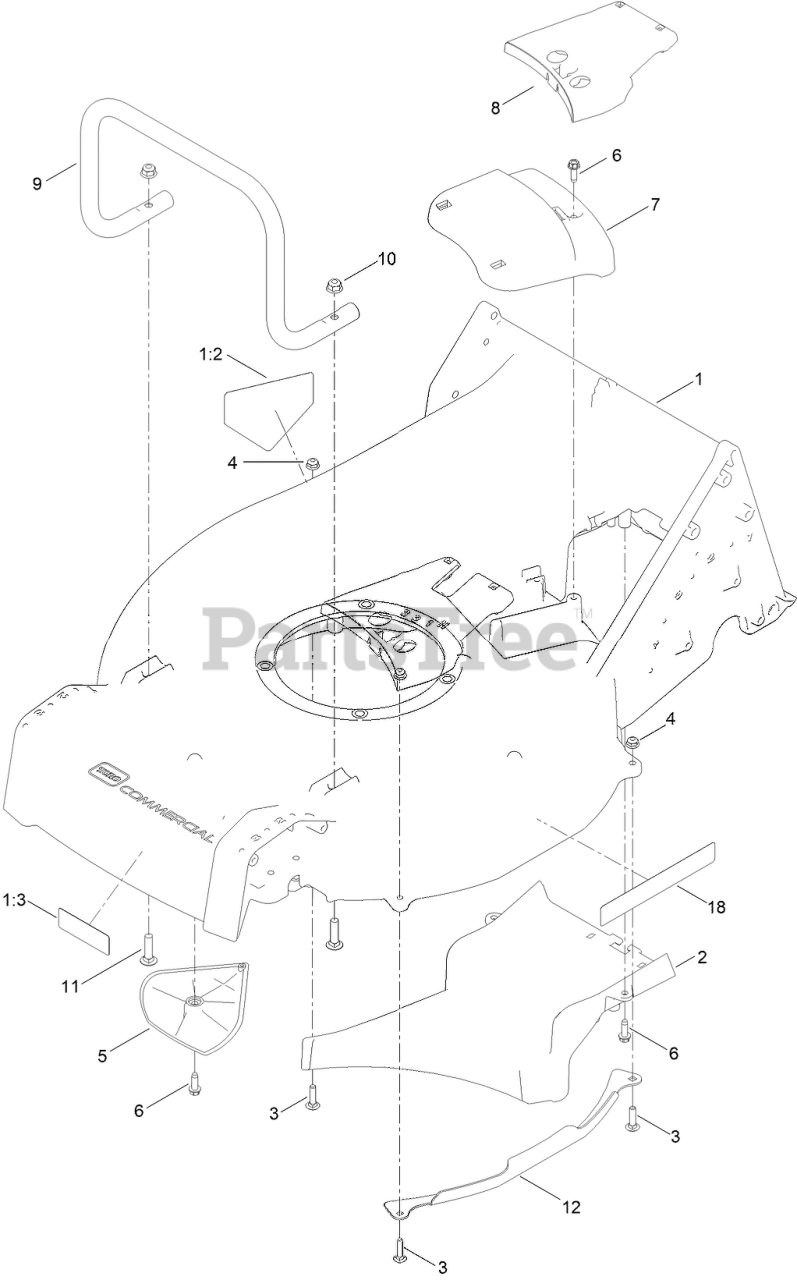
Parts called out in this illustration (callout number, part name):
1	HOUSING ASM
1:2	DECAL-DANGER
1:3	DECAL-WARNING, BLADE
2	FLOOR-CHUTE
3	SCREW-CARR
4	NUT-HF
5	KICKER
6	SCREW-HWHTF
7	COVER-BELT, FRONT
8	COVER-BELT, REAR
9	GUARD-ENGINE
10	NUT-HF, NI
11	SCREW-CARR
12	GUARD-SIDE, DECK
18	DECAL-RECYCLER
